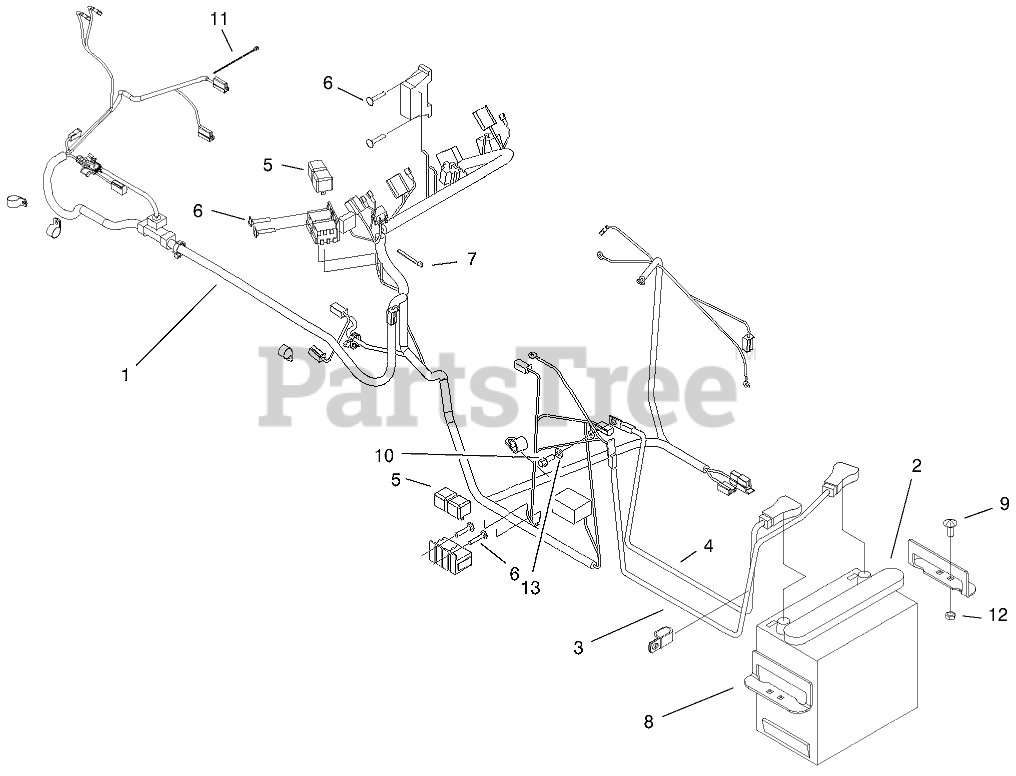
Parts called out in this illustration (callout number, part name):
1	Harness-Main
2	BATTERY - 495CCA
3	CABLE - BATTERY,RED
4	CABLE - BATTERY,
5	RELAY
6	SCREW
7	TIE-CABLE
8	HOLD - DOWN, BATTERY
9	SCREW-CARR
10	SCREW-HH
11	Tie-Cable (only on: 73552)
12	NUT-LOCK, NI
13	WASHER-LOCK
